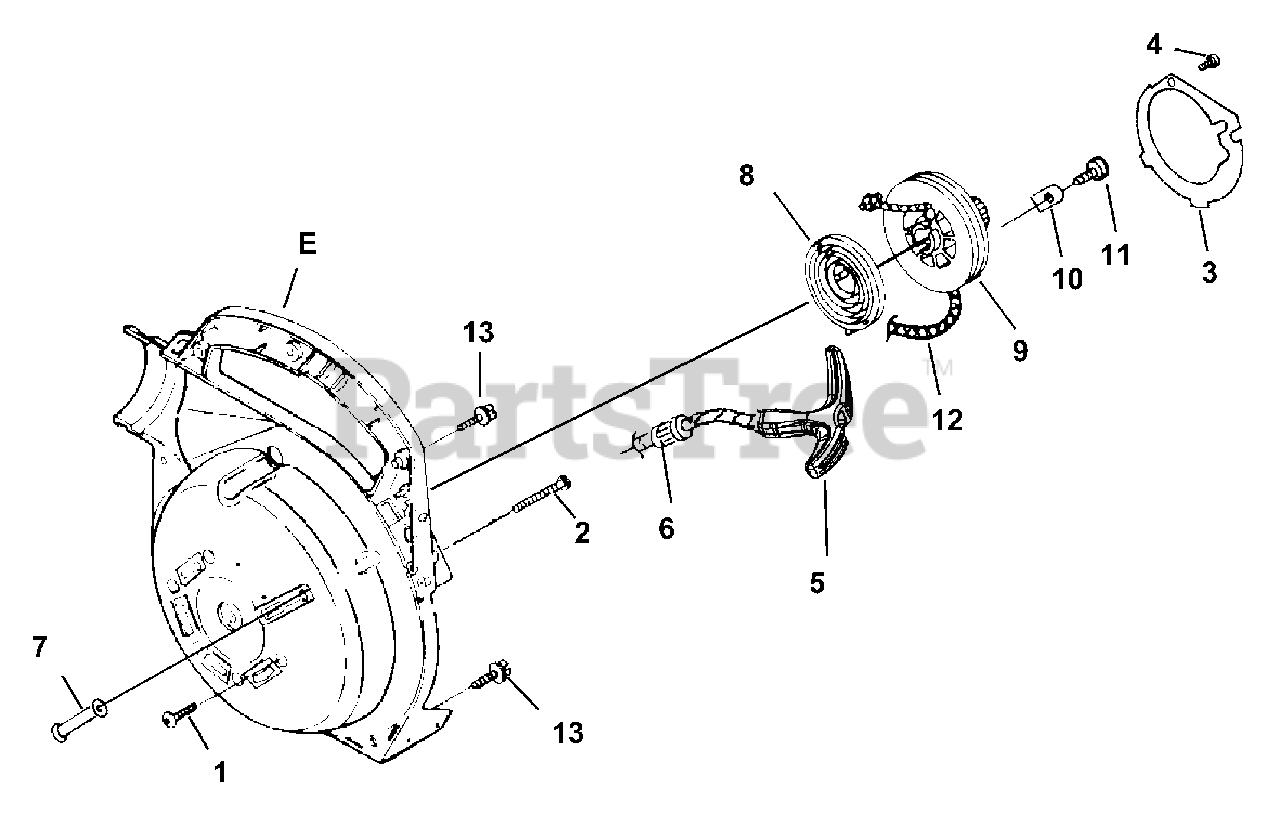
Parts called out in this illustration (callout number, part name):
1	SCREW-Thread Form. (10-24 X 3/4")
2	SCREW-Thread Form. (#10 X 1 5/8")
3	PLATE-Rotor
4	SCREW-Thread Form. (#6 X 1 3/8")
5	GRIP-Starter (Yellow)
6	BUSHING-Starter
7	GUIDE-Starter Rope
8	SPRING & CONTAINER
9	PULLEY-Starter
10	BRACKET-Retaining
11	SCREW-Thread Form. (#10 X 1/2")
12	ROPE-Starter
13	SCREW-Thread Form. (10-24 X 3/4")
E	VOLUTE HOUSING & STARTER
